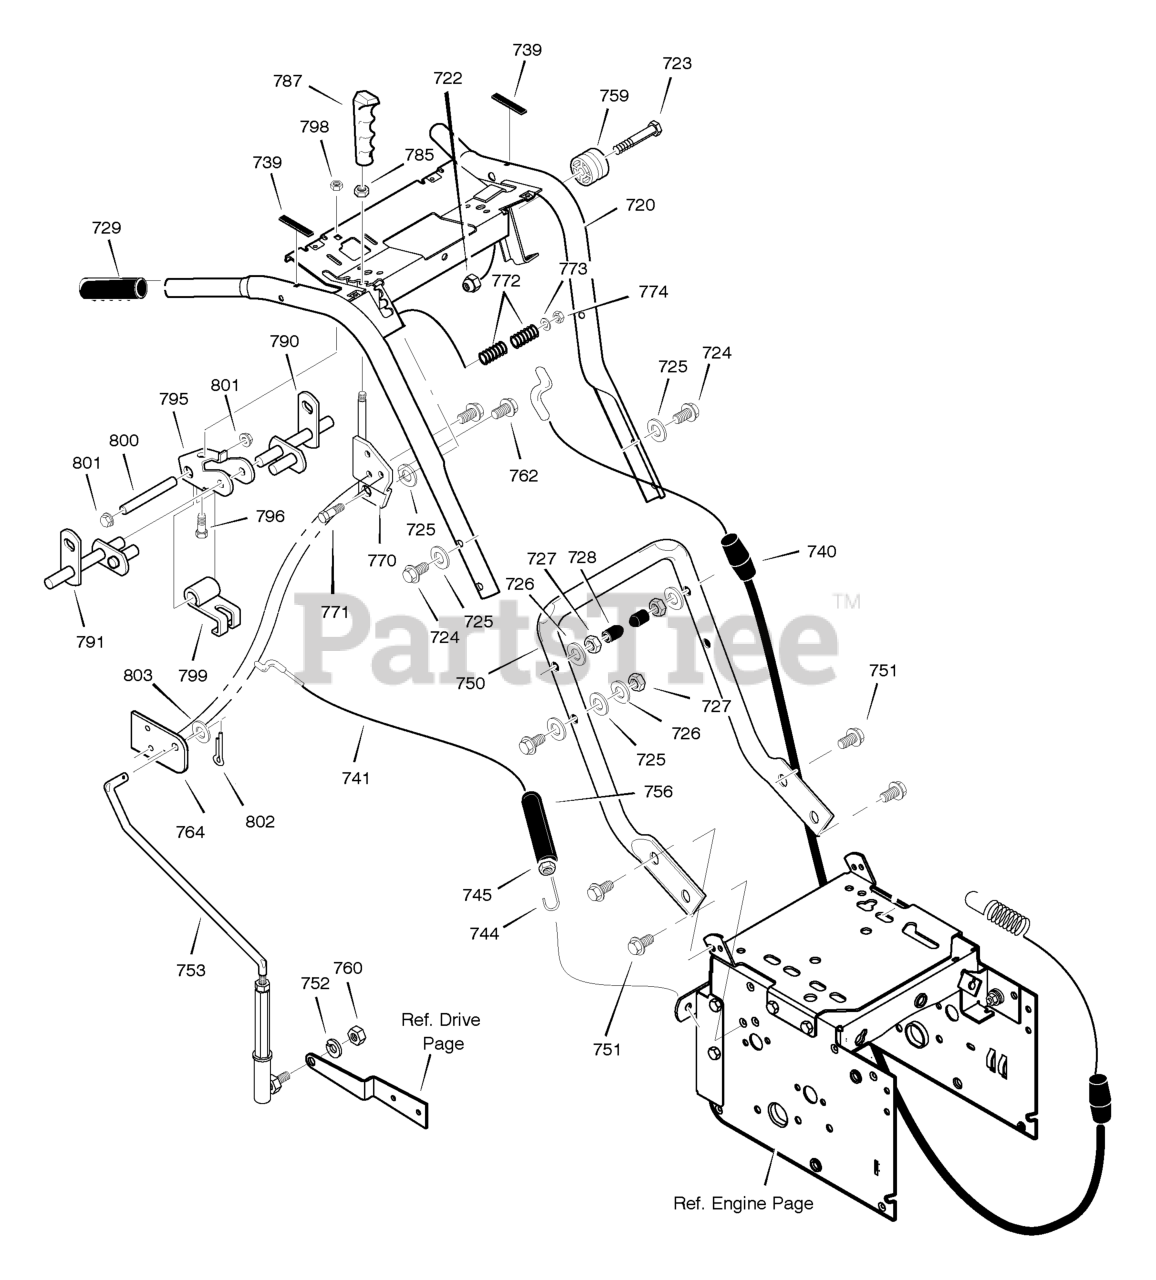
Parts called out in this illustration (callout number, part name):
720	ASSY., HANDLE
722	NUT, 0.25-20 NYLOCK
724	SCREW
725	WASHER
726	WASHER
728	STOP, PLASTIC
729	GRIP, HANDLE
739	BUMPER
740	CABLE, DRIVE
741	CABLE, AUGER
744	SPRING, AUGER CLUTCH
745	NUT, HEX - 1/4-20
750	HANDLE, LOWER
751	SCREW
753	ASSEMBLY, ROD
756	BOOT, SPRING
759	SPOOL, CABLE
760	NUT, 5/16-24
762	SCREW 1/4-20X0.63
764	BRACKET, CONTROL
770	BRACKET, SHIFT
771	SCREW
773	WASHER
774	NUT, HEX, 3/8-16
785	NUT, HEX, 3/8-16
787	KNOB, SHIFT
790	ROD, ASSY LH
791	ROD, ASSY RH
795	BRACKET, CAM
796	SCREW
798	NUT, NYLOCK
799	CAM LOCK
800	PIN, SPRING PIVOT
801	NUT, PUSH ON
802	PIN, COTTER
803	WASHER
